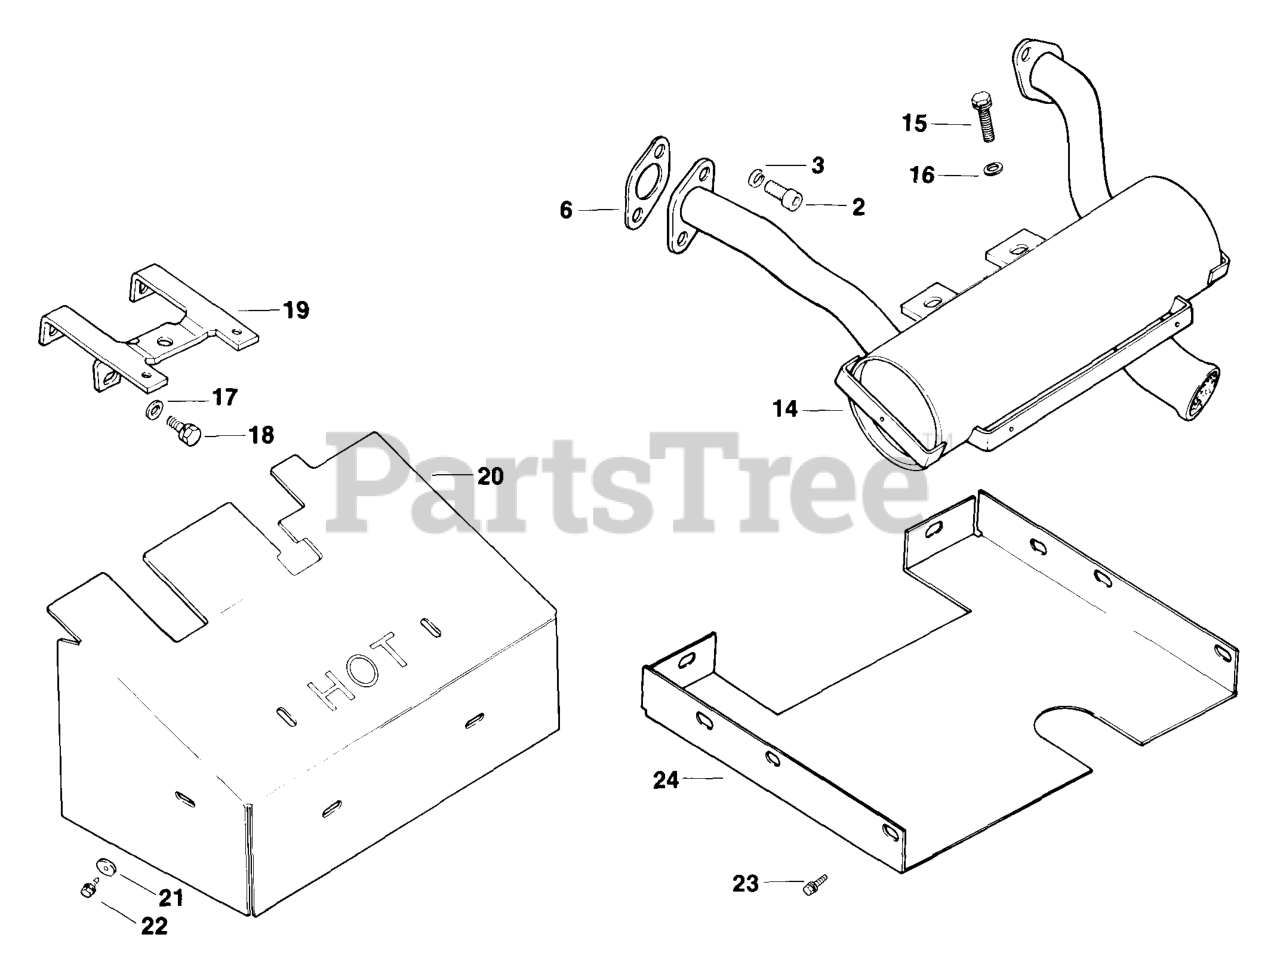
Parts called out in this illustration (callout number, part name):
2	SCREW, HEX SOCKET HEAD CAP USE 25 086 87-S
3	WASHER, SPRING LOCK 5/16"
15	WASHER, FLAT 1/4"
16	SCREW, SEMS 1/4-20-1/2"
17	WASHER, FLAT 1/4"
18	SCREW, WSH HD TAP 1/4-20-5/8" - DISCONTINUED
22	SCREW - USE 25 086 40
